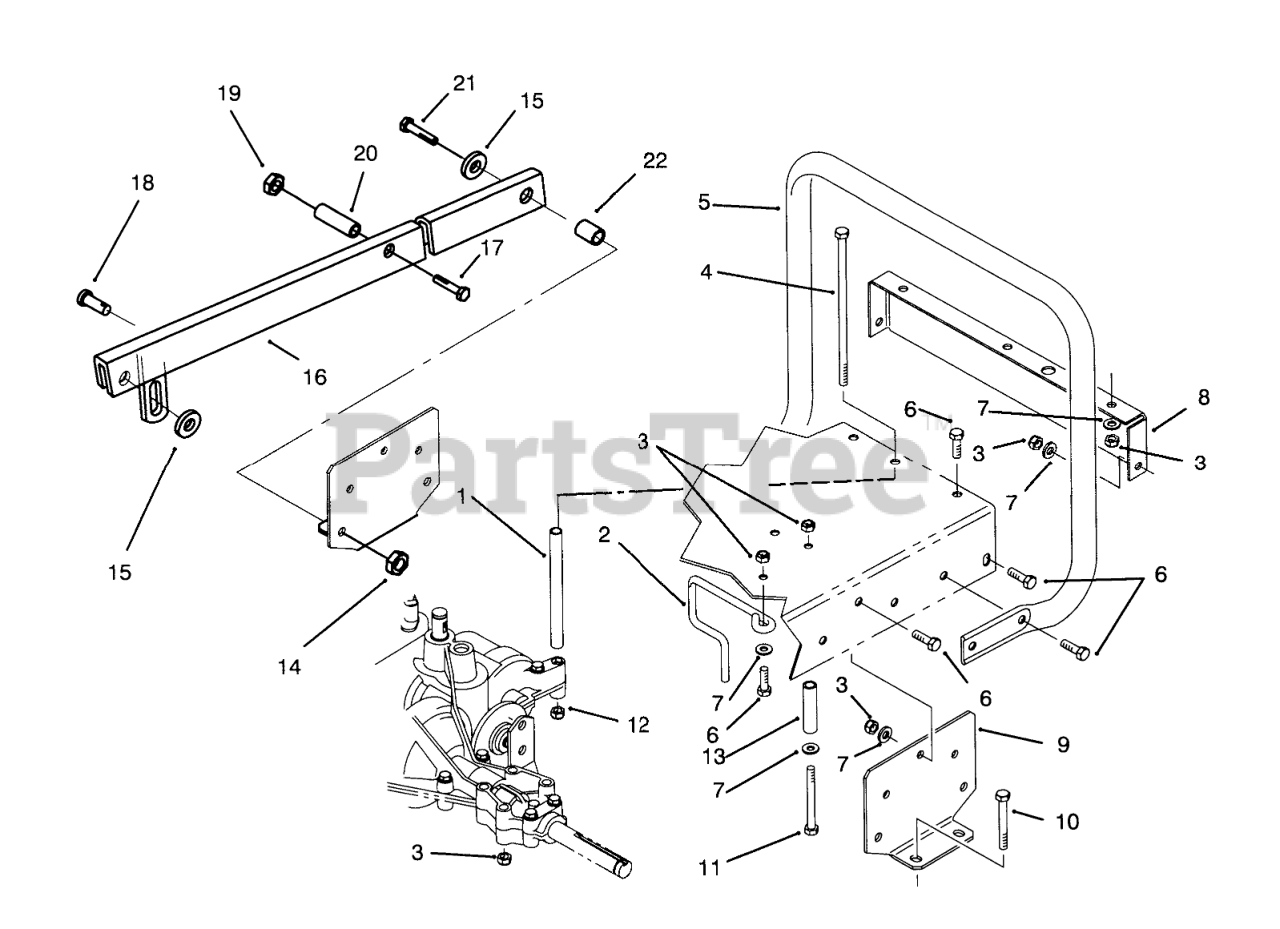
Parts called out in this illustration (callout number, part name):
1	SPACER-TRANSAXLE SUPT
2	GUIDE-ENG BELT
3	NUT-LOCK, NI
4	SCREW-HH
5	Standbar
6	SCREW-HH
7	WASHER-PLAIN
8	Frame-Rear
9	Support-Axle
10	SCREW-HH
11	SCREW-HH
12	NUT-LOCK, NI
13	SPACER-SPLIT TUBE
14	NUT-LOCK, NI
15	WASHER-FLAT
16	Arm-Suspension R.H.
17	SCREW-HH
18	PIN-CLEVIS
19	NUT-LOCK, NI
20	SPACER-SPLIT TUBE
21	SCREW-HH
22	PIN-SUPT ARM
